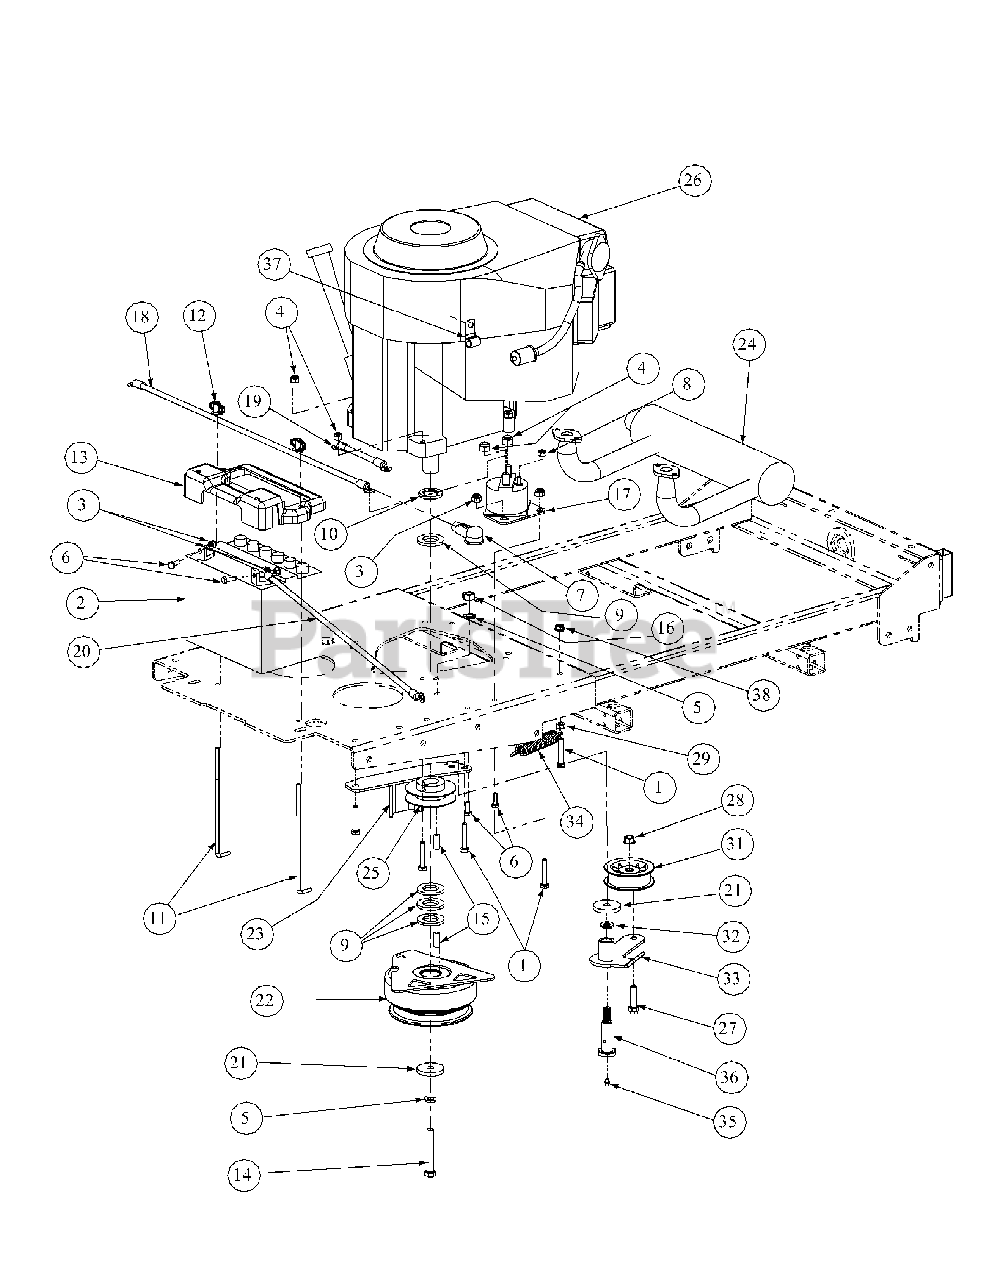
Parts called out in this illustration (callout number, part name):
1	Hex Head Cap Screw, 5/16-18 x 1.75
2	12V Battery
3	Nut, 1/4-20, Nylon Insert
4	Nut, 5/16-18, Nylock
5	Lock Washer, 7/16 Zinc
6	Hex Head Cap Screw, 1/4-20 x .75
7	Rubber Battery Boot, 1.0 OD
8	Nut, 10-32, Nylon Insert
9	Special Washer
10	Engine Pulley Spacer
11	Battery Rod
12	Wing Nut, 1/4-20
13	Large Battery Cover
14	Hex Head Cap Screw, 7/16-20 x 3.00
15	Keystock, 1/4 x 1/4 x 0.875
16	Hex Nut, 7/16-14
17	Solenoid Switch
18	Battery Cable, 24.0", Red
19	Battery Cable, 5.0", Red
20	Battery Cable, 28.0", Black
21	Washer, 7/16 ID x 1.75 OD x .250
22	Brake Clutch, 1.0 OD
23	Clutch Retainer Assembly
25	Cast Pulley, 3.25 OD x 1.0 ID
26	17HP Kawasaki Engine
27	Hex Cap Screw, 3/8-16 x 1-1/2
28	Hex Flange Lock Nut, 3/8-16
29	Nut, 5/16-18
31	Idler Pulley w/ Adaptor
32	Washer, .469 ID x .875 OD x .105
33	Idler Arm Assembly
34	Extension Spring, 1.00 OD x 5.00
35	Grease Fitting
36	Shoulder Screw
37	Wire Clip
38	Nut, 5/16-18, Hex Flange Lock
